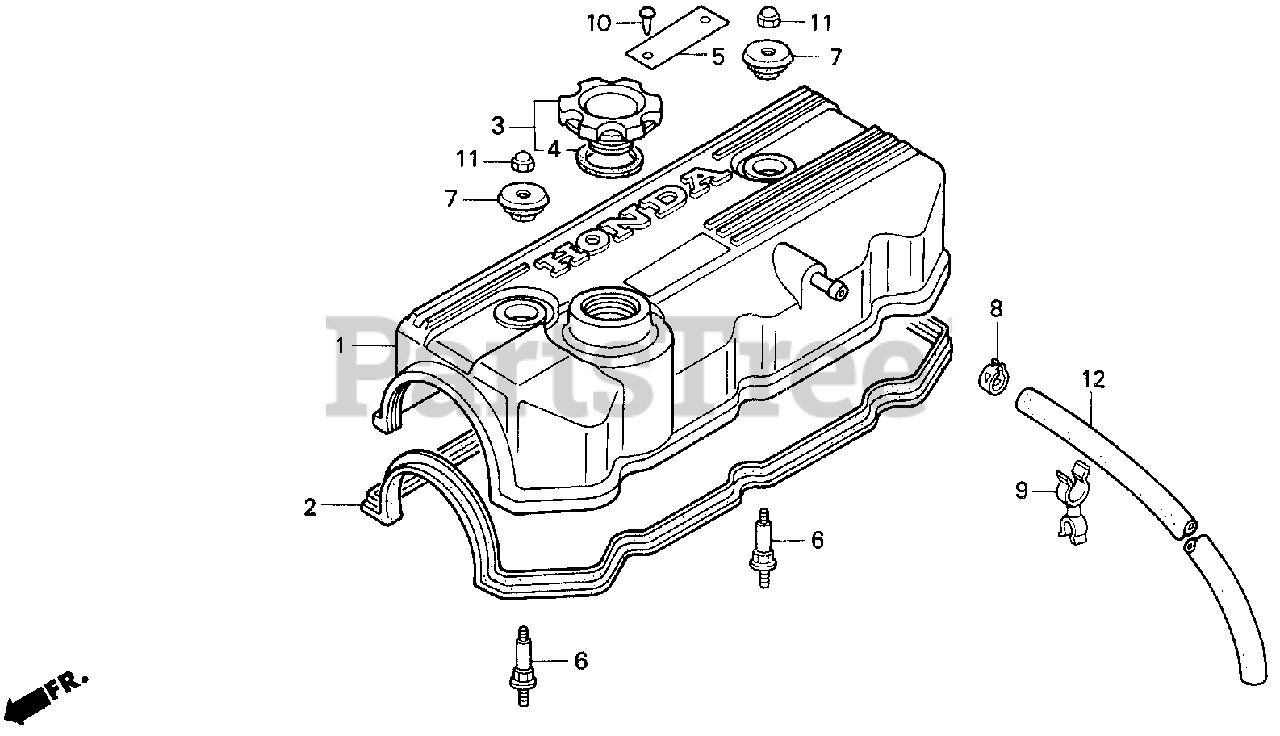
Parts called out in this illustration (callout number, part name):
1	COVER, HEAD
2	GASKET, HEAD COVER
3	CAP ASSY., OIL FILLER
4	GASKET, OIL FILLER
5	LABEL, SPECIFICATION (J)
6	BOLT, HEAD COVER
7	WASHER, HEAD COVER
8	CLAMP, CANISTER HOSE
9	CLAMP, PIPE (B)
10	RIVET, SCREW (1.8MM)
11	NUT, CAP (6MM)
12	BULK HOSE, VACUUM (11X1000) (11X440)
